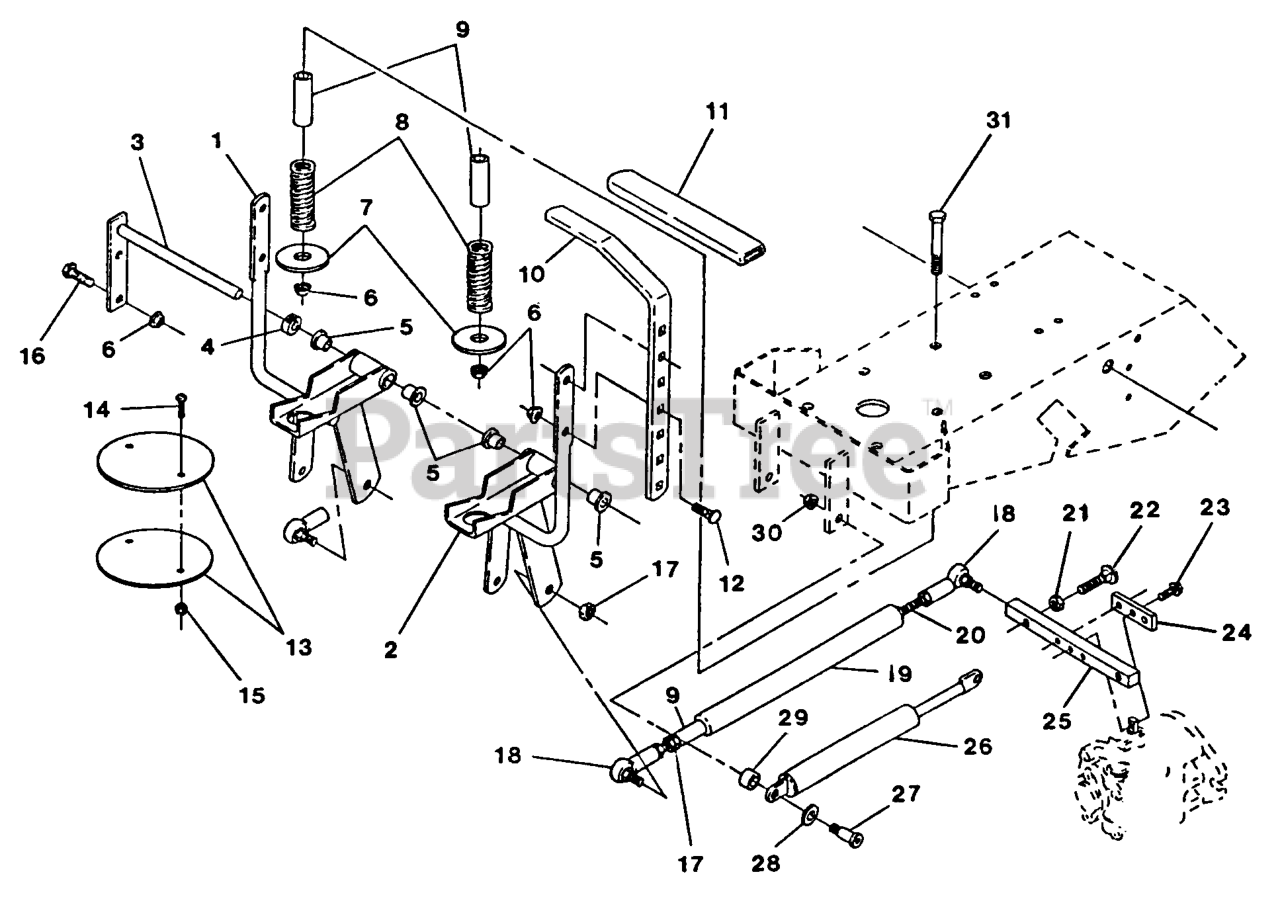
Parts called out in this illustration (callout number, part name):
5	BEARING-CONTROL
7	WSHR,REVERSE INDICATOR
8	SPRING-INDICATOR, REVERSE
9	BUSHING,SPRING GUIDE
11	GRIP,MOTION CONTRL
18	BALLJOINT
20	ROD,STEERING
24	PLATE,CLAMP
25	ARM,PUMP CONTROL
29	SPACER-PLATED
